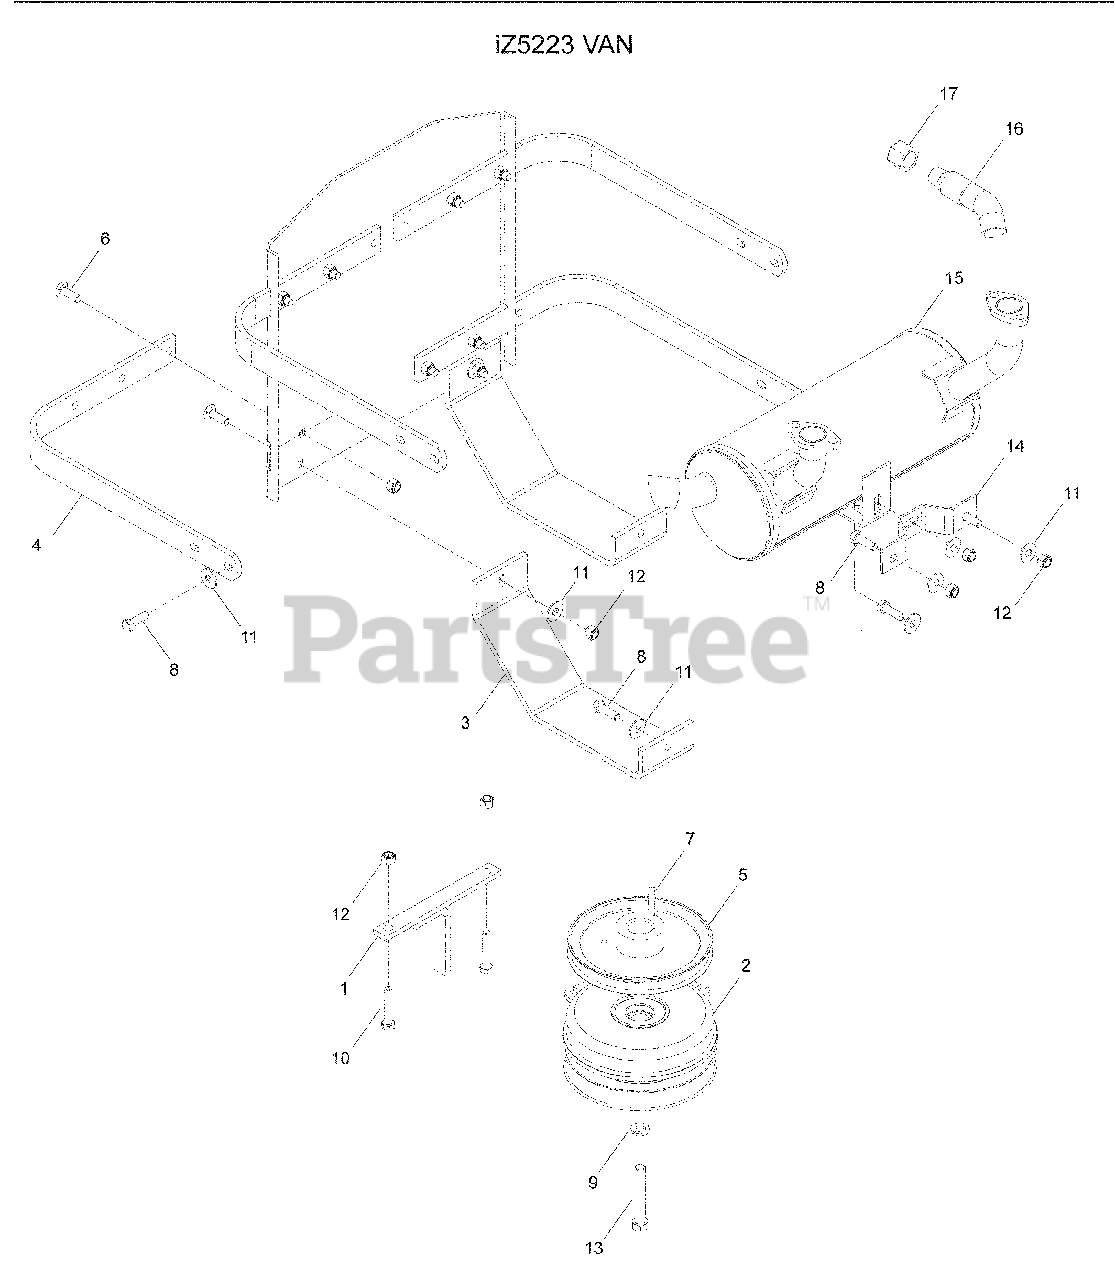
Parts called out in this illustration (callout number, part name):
1	TIE DOWN, CLUTCH
2	CLUTCH, 200 FT/LB
3	SKID PLATE
4	STRAP, BLACK
6	RHSNB 5/16-18 x 1
7	KEY ¼ SQ x 1¼
8	HCS 5/16-18 x 1
9	WASHER 7/16 SLW
10	HCS 5/16-18 x 1¾
11	WASHER 5/16 STD FLT
12	NUT 5/16-18 HEX NYLOC
13	HCS 7/16-20 x 2¾
14	BRACKET, MUFFLER
15	MUFFLER, VANGUARD
16	HOSE, DRAIN
